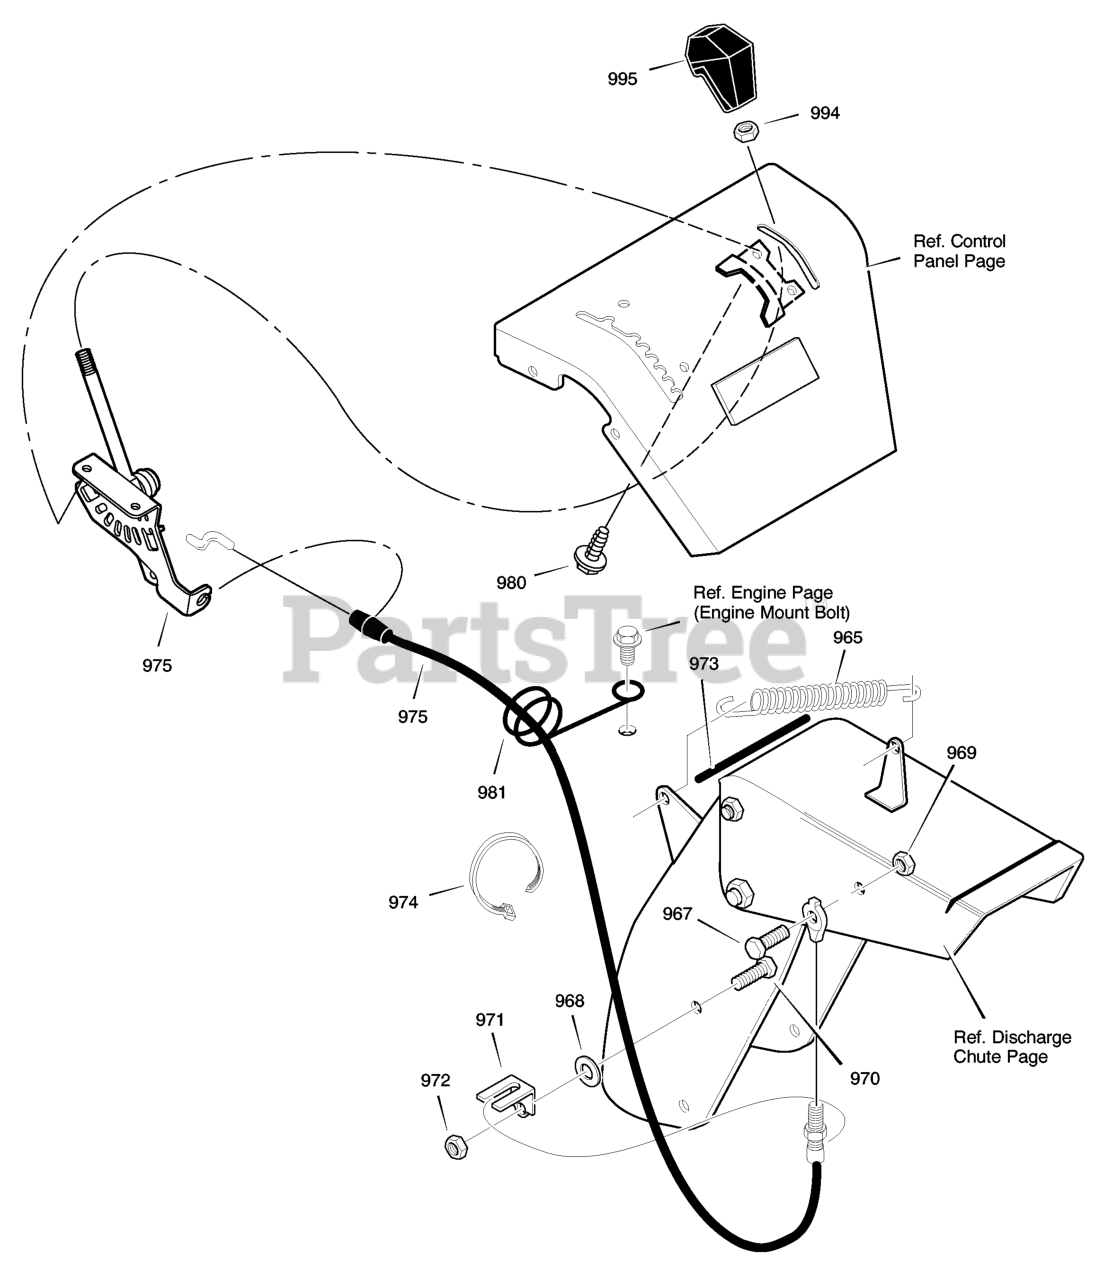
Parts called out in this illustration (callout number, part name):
965	TENSION SPRING
968	FLATWASHER
971	BRACKET, CABLE CHUTE
972	NUT
973	TRIM STRIP, GREY
974	TIE, CABLE
975	ASSY, CHUTE DEF. CONTROL
980	SCREW
981	WIRE FORM, REMOTE CHUTE CABLE
995	KNOB, SHIFT (GREY)
